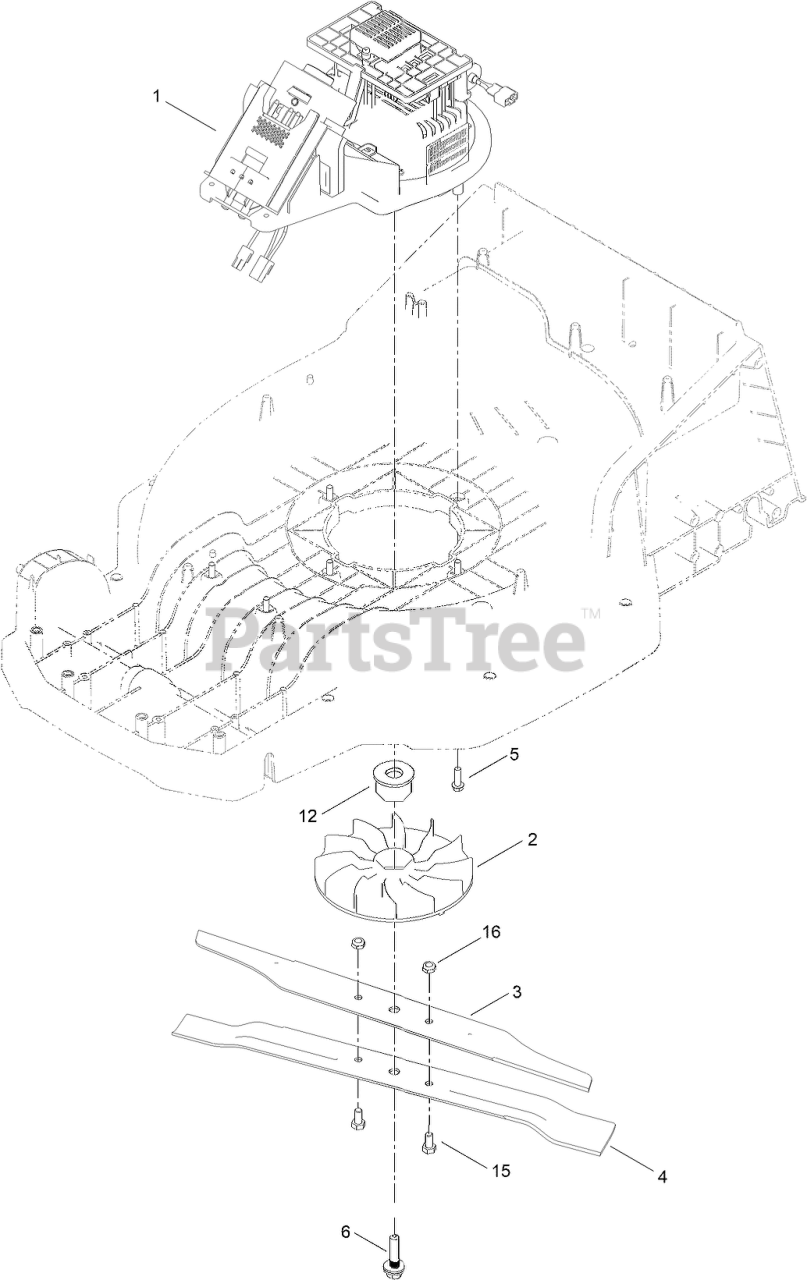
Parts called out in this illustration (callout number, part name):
1	ASM-POWER. COBRA SP (w/LED)
2	FAN-MOTOR
3	BLADE-TOP, 20.25"
4	BLADE-BOTTOM, 20.25"
5	SCREW-HWH
6	BOLT-BLADE, SEMS
12	INSERT-FAN, MOTOR
15	SCREW-HH
16	NUT-HEX
